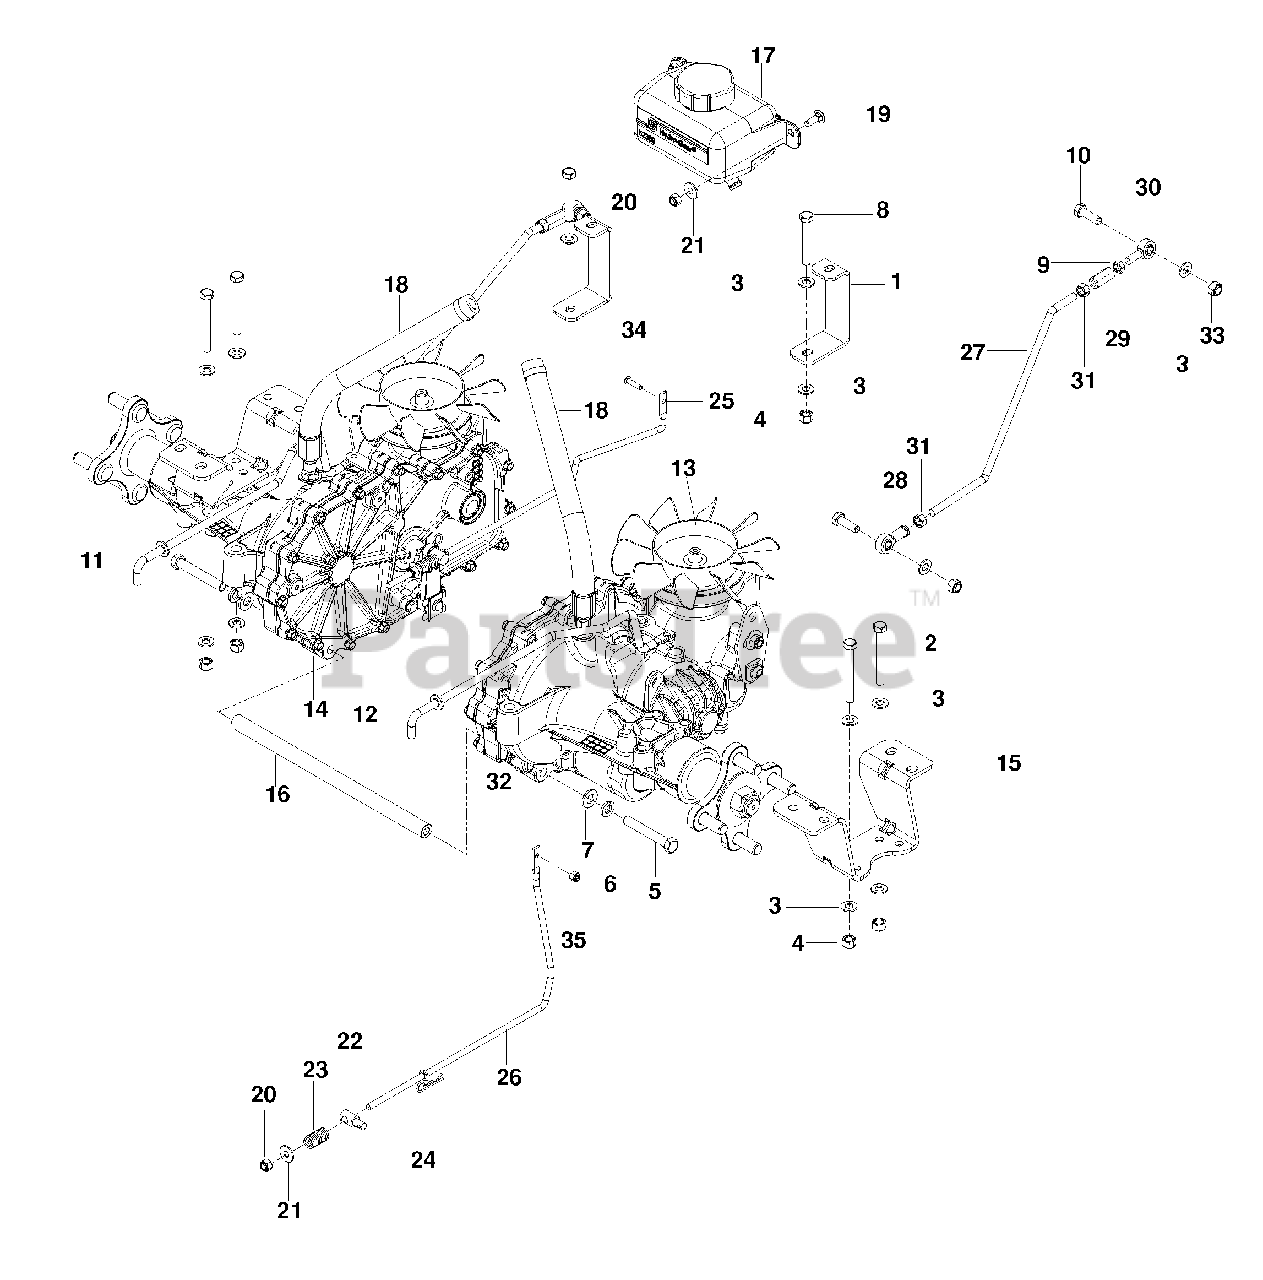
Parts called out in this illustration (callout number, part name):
1	Support, Transmission
2	Hcs 5/16-18 X 2 3/4
3	Washer 5/16 Sae Flat
4	Nut 5/16-18 Hex Nyloc
5	Hcs 3/8-16 X 2 1/2
6	Washer 3/8 Splt Lock
7	Washer 3/8 Sae Flat
8	Hcs 5/16-18 X 2 1/4
9	Nut 5/16-24 Hex Jam Lh
10	Hcs 5/16-18 X 1
11	Link Arm, Bypass, Rt
12	Link Arm, Bypass, Lt
13	Trans, Zt-2800 Rt
14	Trans, Zt-2800 Lt
15	Ezt Mount, Rear
16	Spacer Tube, Ezt
17	Expansion Tank W/Cap
19	Rhsnb 1/4-20 X 3/4 Gr2
20	Nut 1/4-20 Hex Nyloc
21	Washer 1/4 Flat
22	Brake Swivel
24	Hairpin Cotter
25	Linkage, Brake Lt
26	Linkage, Brake Rt
27	Rod, Motion Control
28	Rod End Rh
29	Coupler, Rod End
30	Rod End Male Lh
31	Nut 5/16-24 Hex
33	Nut 5/16-18, Nyloc
34	Screw, #10-24 X 3/4
35	Nut 10-24 Hex Nyloc
